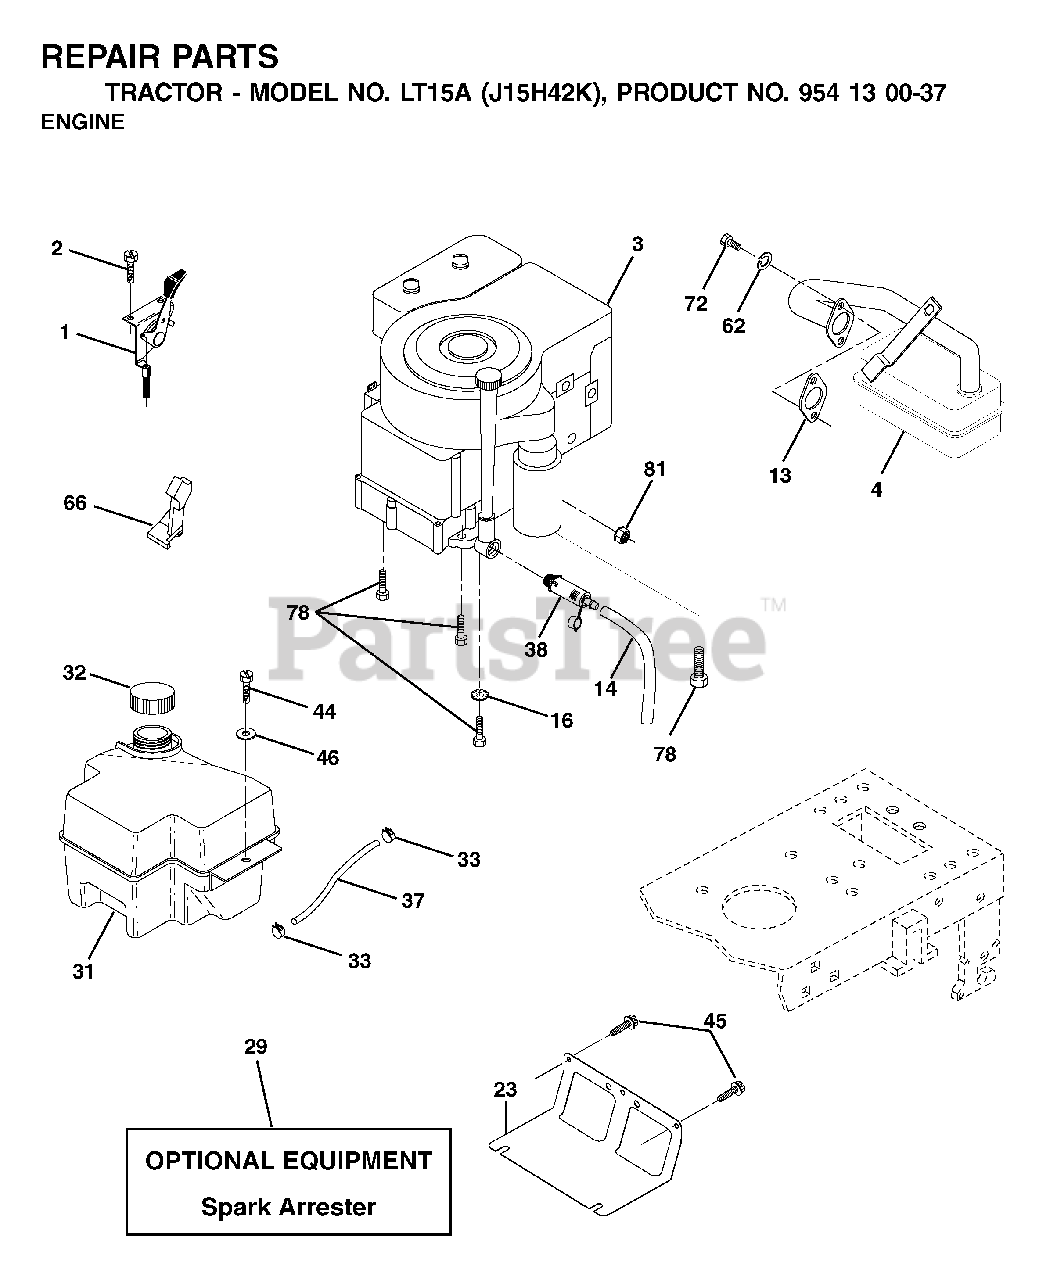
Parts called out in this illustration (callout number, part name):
1	THROTTLE CONTROL CABLE
2	SCREW LT
13	REPL BY 532 27 22-93
14	TUBE, DRAIN OIL ASM.
16	LOCKWASHER
23	SHEILD.BROWNING.DBR.GUARD
29	ARRESTER SPARK (OPTIONAL)
31	TANK, 2GAL
32	FUEL CAP
33	HOSE CLAMP
37	LINE.FUEL.20
38	PLUG, OIL DRAIN EASY
40	GROMMET T
44	SCREW HEXWSHR 1/4-20X3/4
45	SCREW, 3/8-16X3/4
62	LOCKWASHER
66	STOP THROTTLE
72	SCREW
78	SCREW.3/8-16
81	NUT
